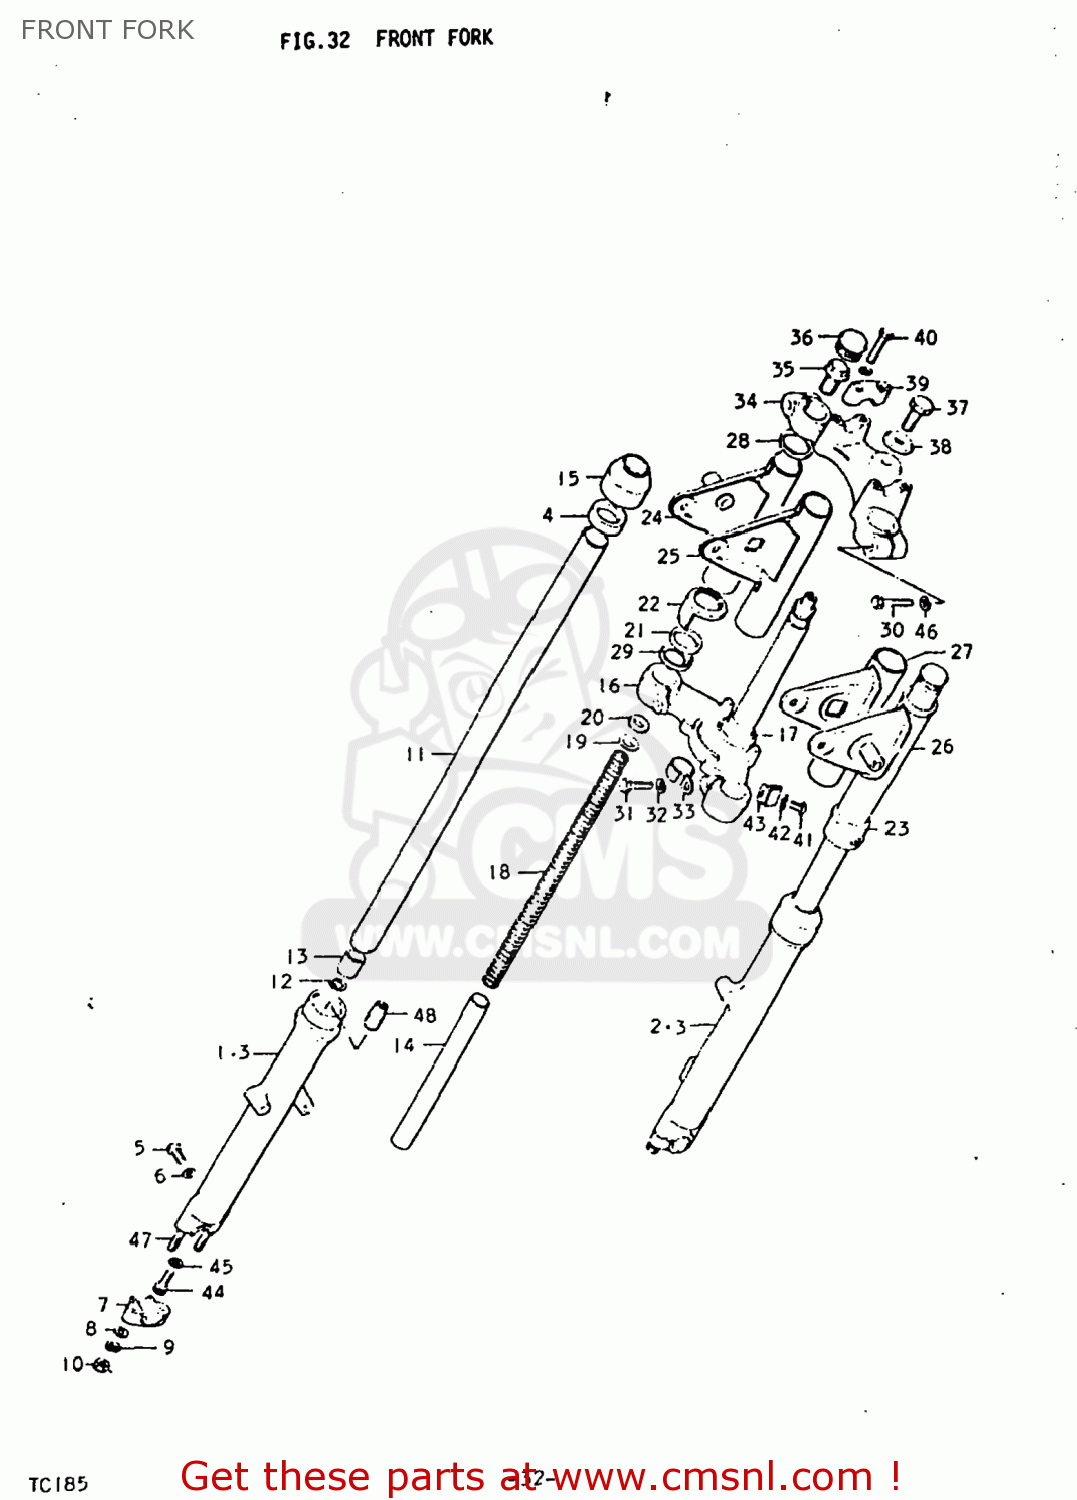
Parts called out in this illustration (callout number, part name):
0	DAMPER SET
1	TUBE,OUTER,RIGHT
2	TUBE,OUTER,LEFT
3	TUBE,OUTER,LEFT
4	SEAL,OIL
5	SCREW
6	GASKET,DRAIN,PLUG (NAS)
7	HOLDER,AXLE
8	WASHER
9	LOCK WASHER
10	NUT (8MM)
11	TUBE,FORK,INNER
12	SNAP RING
13	PISTON
14	CYLINDER,FRONT FORK
15	SEAL,DUST
16	STEM,STEERING
17	RACE,STEERING OUTER LWR
18	SPRING,FRONT FORK
19	GUIDE,SPRING
20	SEAT,SPRING
21	CUSHION,HEADLAMP BRACKET
22	CUSHION,HEADLAMP BRACKET
24	BRACKET,HEADLAMP HOUSING
25	BRACKET,HEADLAMP HOUSING
26	BRACKET,HEADLAMP,LEFT
27	BRACKET,HEADLAMP,LEFT
28	SEAT,HEADLAMP BRACKET
29	GUIDE, COVER
30	BOLT,FORK INNER TUBE F
31	BOLT,FR FORK LWR(12X33)
32	WASHER,LOCK 12
33	CLIP
34	HEAD,STEERING STEM
35	CAP
36	CAP,FRONT FORK
37	BOLT,FORK INNER TUBE
38	WASHER
39	HOLDER,HANDLEBAR
40	Bolt
41	SCREW
42	LOCK WASHER
43	CLIP
44	BOLT
45	GASKET
46	LOCK WASHER
47	BOLT,STUD
48	PIECE,OIL LOCK
